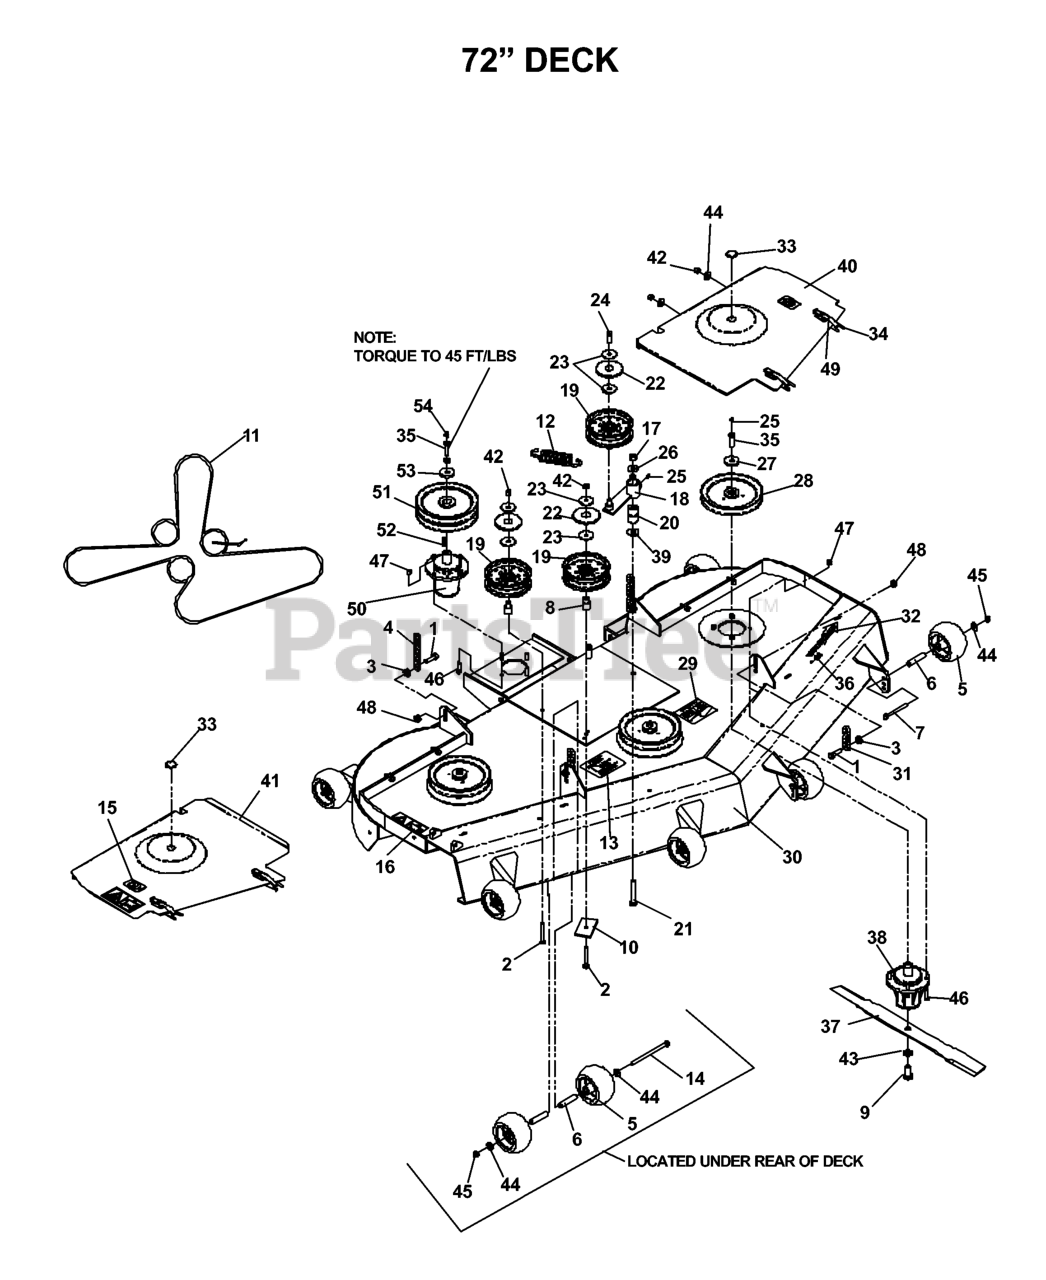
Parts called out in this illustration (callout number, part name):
1	HCS 7/16C X 1 1/2
2	HCS 3/8C X 3
3	NUT 7/16C WHIZ
4	LIFT CHAIN
5	ANTI-SCALP ROLLER
7	HCS 3/8C X 3 1/2
8	IDLER BUSHING
9	HCS 5/8F X 1 1/4
10	SUPPORT PLATE
11	BELT, DECK
12	DECK SPRING
13	DECAL, ANTI SCALP
14	BOLT 3/8 X 6" GRD 8
15	DECAL, NO STEP
16	DECAL, EURO SEVERING
17	NUT 1/2-13 HEX NYLOC ZD
19	IDLER PULLEY
20	PIVOT BUSHING
21	HCS 1/2C X 3 1/4
22	TOP DUST CAP
23	WASHER, 3/8 SPEC
24	HCS 3/8C X 1 1/4 GR5
25	ZERK
26	WASHER 1/2 FLAT
27	SPINDLE WASHER
28	RP PULLEY - 72"
29	DECAL, BELT ROUTING
30	DECK W/DECALS
31	LIFT CHAIN - 3 LINK
32	DECAL, TUNNEL RAM 8"
33	BUTTON PLUG - 1" NOM.
35	HCS 7/16-20 GD 8 SPEC
36	DECAL, 183
37	BLADE, 25"
38	HOUSING ASM, 52/61
39	WASHER 1/2 X 1.44 HRD ZD
40	72 BELT SHIELD ASM LH
41	72 BELT SHIELD ASM - RH
42	NUT 3/8-16 NYLOC
43	LOCKWASHER 5/8
44	WASHER 3/8 FLAT
45	NUT 3/8C CENTERBLOCK
46	HCS 5/16C X 1 1/4
47	NUT 5/16 NYLOC
48	NUT 7/16C CENTERLOCK
49	DRAW LATCH
50	BAM L44 JACKSHAFT ASM LOWER
51	SHEAVE WSL
52	KEY 1/4 SQ X 1 1/8
53	SPINDLE WASHER
